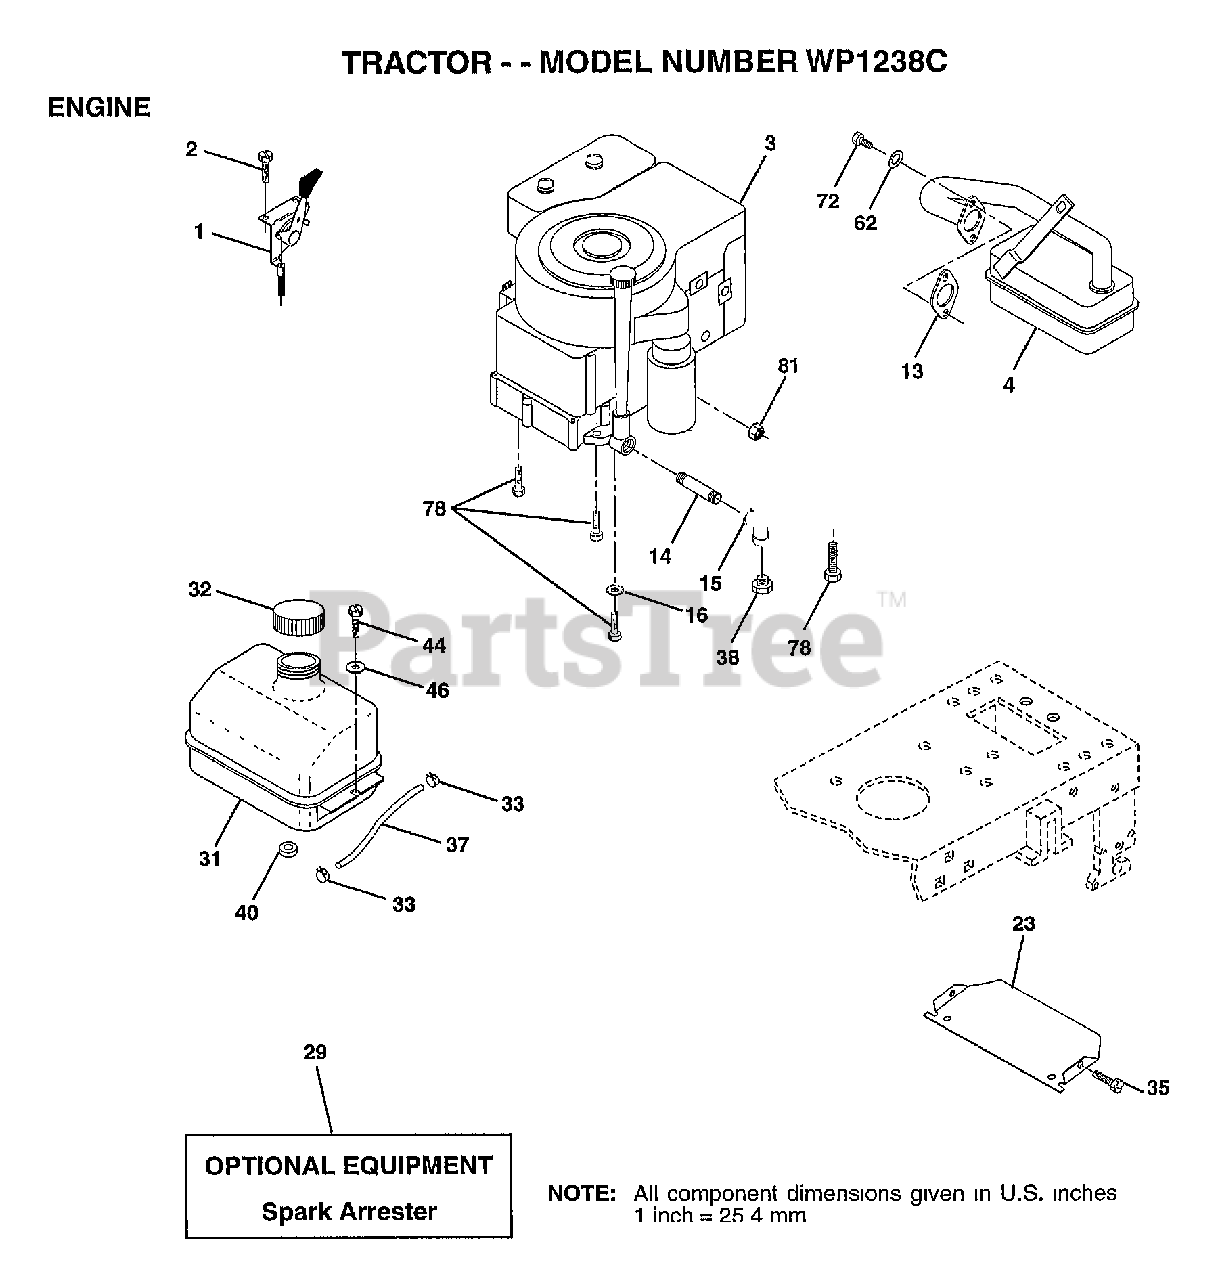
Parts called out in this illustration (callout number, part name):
1	THROTTLE CONTROL
2	SCREW LT
4	MUFFLER
13	GASKET ENG 1 313 LD TIN PLATED
14	PIPE NIPPLE
15	ELBOW
16	LOCKWASHER
23	SHIELD-HEAT
31	TANK.FUEL.LT.
32	CAP ASM FUEL
33	HOSE CLAMP
35	SCREW
37	LINE FUEL
44	SCREW HEX CRT
46	WASHER
62	LOCKWASHER
72	SCREW
78	SCREW
81	NUT
